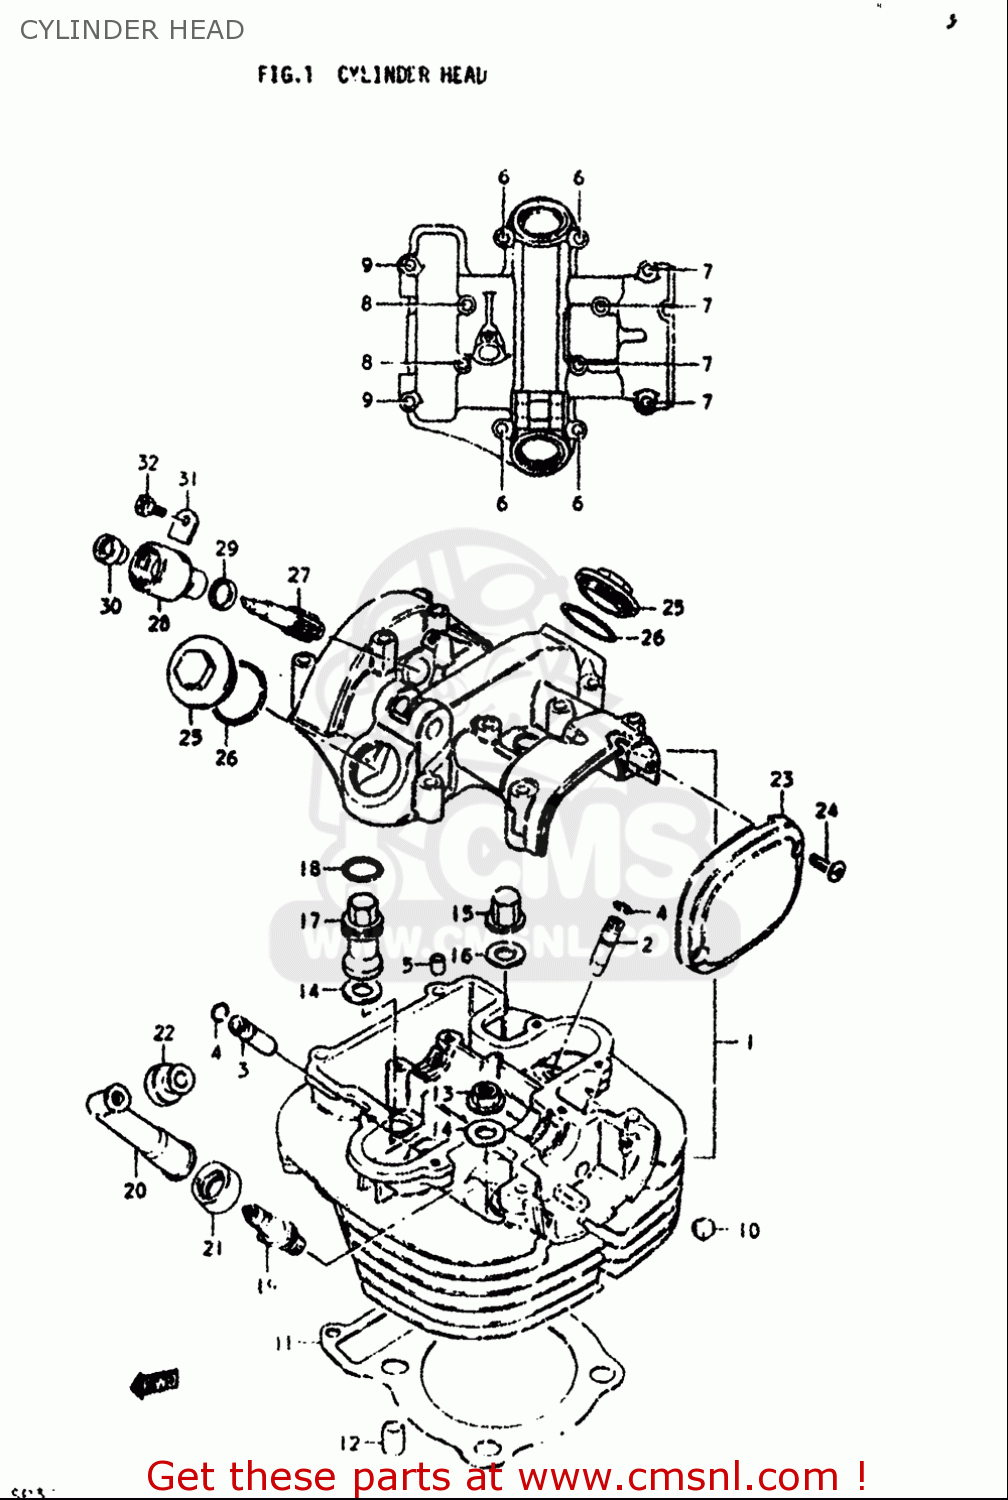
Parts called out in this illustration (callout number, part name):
2	GUIDE,INTAKE VALVE
3	GUIDE,EXHAUST VALVE
4	RING,SNAP
5	PIN(6.2X8X11)
6	BOLT
7	BOLT
8	BOLT
10	PAD,CYLINDER RUBBER(N1)
11	GASKET,CYLINDER HEAD (NAS)
12	PIN
13	NUT
14	WASHER(10.5X22X2.3)
15	NUT
16	GASKET(10.5X22X2) (NAS)
17	NUT,CYLINDER HEAD SEAL
18	O RING(D:2.4,ID:17.8)
19	SPARK PLUG D8EA
20	CAP ASSY,SPARK PLUG
21	SEAL,SPARK PLUG
22	SEAL,HIGH TENSION CORD
24	SCREW
25	CAP,INSPECTION
26	O RING(D:3,ID:29.5)
27	GEAR,TACHOMETER DRIVEN
28	SLEEVE,TACHOMETER DRIVE GEAR
29	SEAL,TACHOMETER DRIVEN
30	SEAL,OIL(5X12X8)
31	PLATE,TACH DRIVE GEAR SLEEVE
32	SCREW(5X12)
